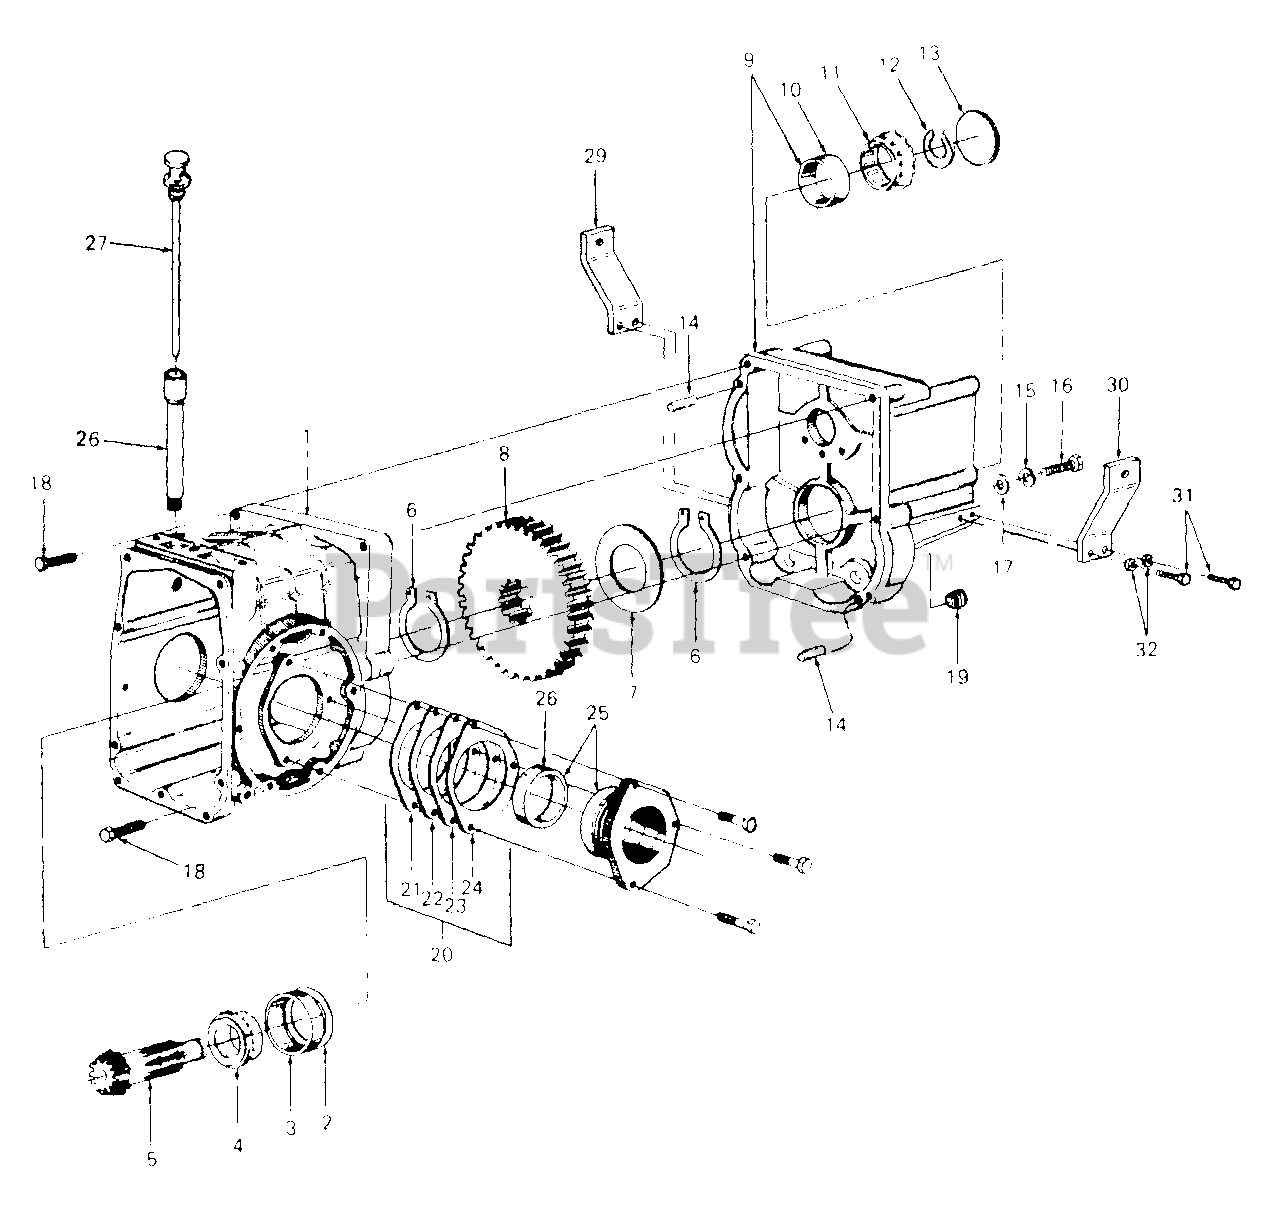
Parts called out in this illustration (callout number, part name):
1	Housing Assy, Rear Transaxle (Includes Ref No. 2 & 3)
2	Shim, Rear Bearing Cup, .004 Thk Qty of AR can also be used
3	Cup, Roller Bearing
4	Cone, Roller Bearing
5	Shaft, Bevel Pinion NOTE: Proper selection of Ref No. 12 is required when replacing 717-3070.
6	Ring, Retaining, 1.312 Dia
7	Spacer, Gear
8	Gear, Reduction - 66T
9	Housing Assy, Adapter w/Cup Includes Ref No. 10
10	Cup, Roller Bearing
11	Cone, Roller Bearing
12	Retainer, Front Bearing, .125 Thk
13	Plug, Expansion, 2.12 OD
14	Pin, Dowel, 3/8 Dia x 5/8 Lg
15	Washer, Spring, .445 x .75 x .017 Thk
16	Screw, Hex Cap, 7/16-14 x 2.5 Lg GR5
17	Washer, Flat, .46 x .875 x .060 Thk
18	Bolt, Hex Patch, 7/16-14 x 1.75 Lg GR5
19	Plug, Drain NOTE: Use Teflon Sealing Tape
20	Shim Package (Includes Ref No. 21 (Qty 3), 22 (Qty 4), 23 (Qty 2) & 24 (Qty 2)
21	Shim, Bearing Retainer, .004 Thk
22	Shim, Bearing Retainer, .007 Thk
23	Shim, Bearing Retainer, .014 Thk
24	Shim, Bearing Retainer, .028 Thk
25	Retainer Assy, Bearing w/Cup Includes Ref No. 26
26	Cup, Roller Bearing
26	Tube, Dipstick NOTE: Use Teflon Sealing Tape
27	Blade Assy, Dipstick
29	Bracket, Trans Mtg - LH
30	Bracket, Trans Mtg - RH
31	Bolt, Hex Patch, 3/8-16 x 1.0 Lg GR5
32	Washer, Lock, 3/8
